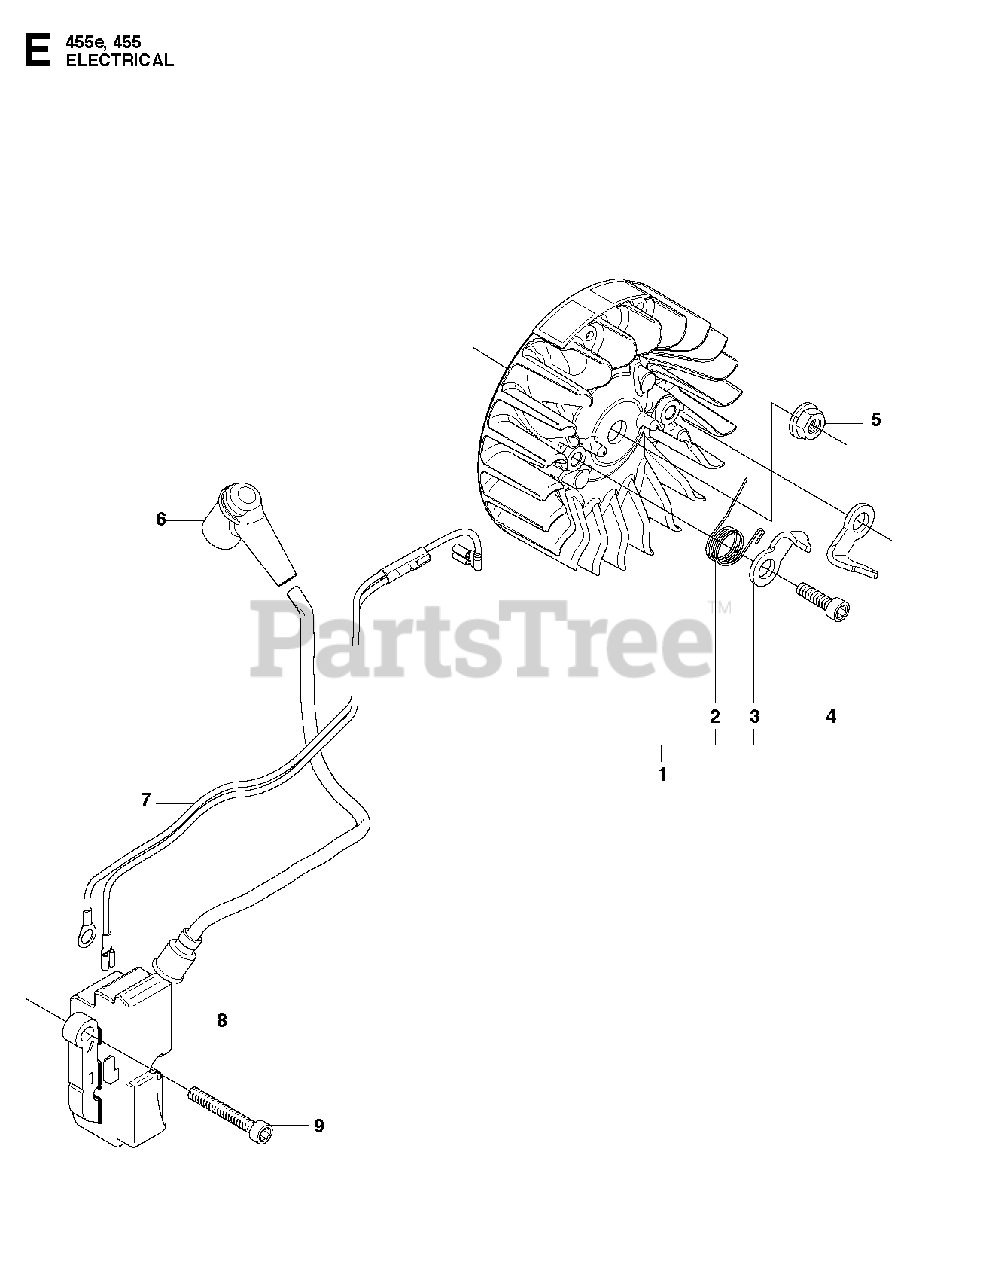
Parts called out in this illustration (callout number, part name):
2	SPRING
3	PAWL
4	SCREW
5	NUT W/ WASHER
6	SPARK PLUG CONN. KIT
7	CABLE ASSY
8	IGNITION MODULE
